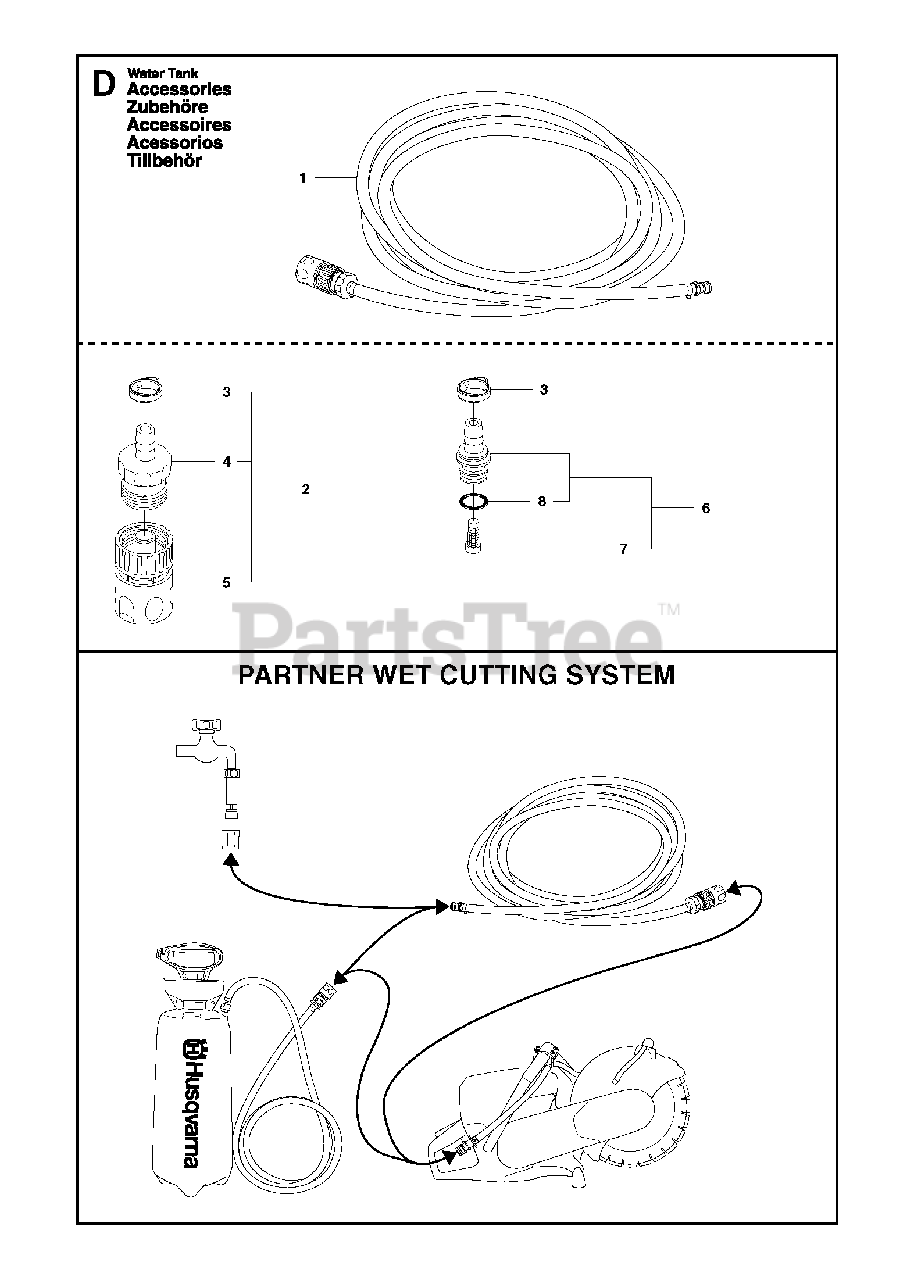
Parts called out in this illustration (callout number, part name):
2	HOSE COUPLINGIncl. 3, 4, 5
3	HOSE CLAMP
5	COUPLER
6	NIPPLEIncl. 7, 8
8	O-RING
